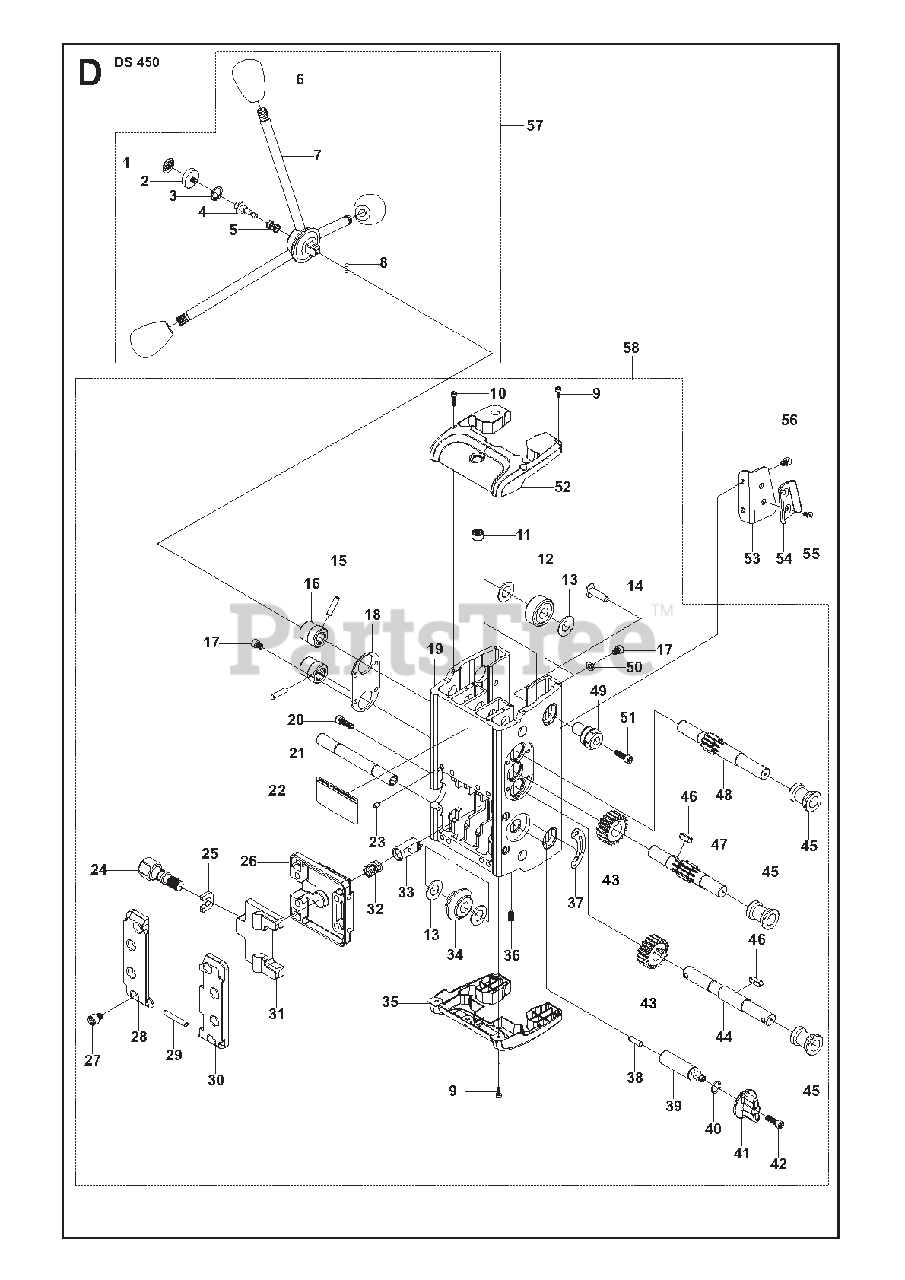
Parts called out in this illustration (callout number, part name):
15	PARALLEL PIN
20	SCREW IHSCM
23	PARALLEL PIN
51	SCREW IHSCM
